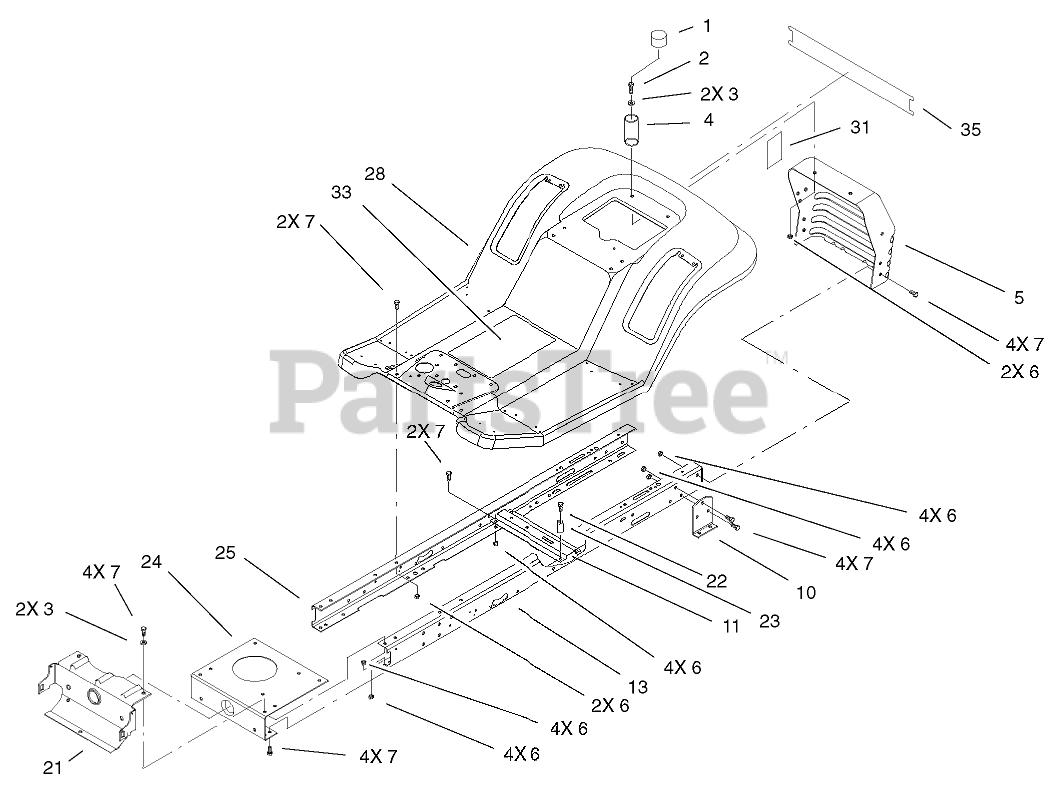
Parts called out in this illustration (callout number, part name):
1	CAP-PROTECTOR
2	SCREW-HH
3	WASHER-PLAIN
4	SPRING-COMPRESSION
5	SUPPORT-SEAT/REAR HITCH
6	NUT-LOCK, NI
7	SCREW-HH
10	BRACKET-TRANSAXLE, MOUNTING
11	BRACKET-IDLER PIVOT
13	RAIL-FRAME, LH
21	SUPPORT-FRONT, AXLE
22	SCREW-HH
23	SPACER
24	PLATE-MOUNTING, ENGINE
25	RAIL-FRAME, RH
28	REAR BODY ASM
31	DECAL-VALVE, DUMP
33	Decal-Instruction, Hydro (only on: 71227)
33	Decal-Instruction (only on: 71242)
35	DECAL-REAR FENDER, LAWN TRACTORS
